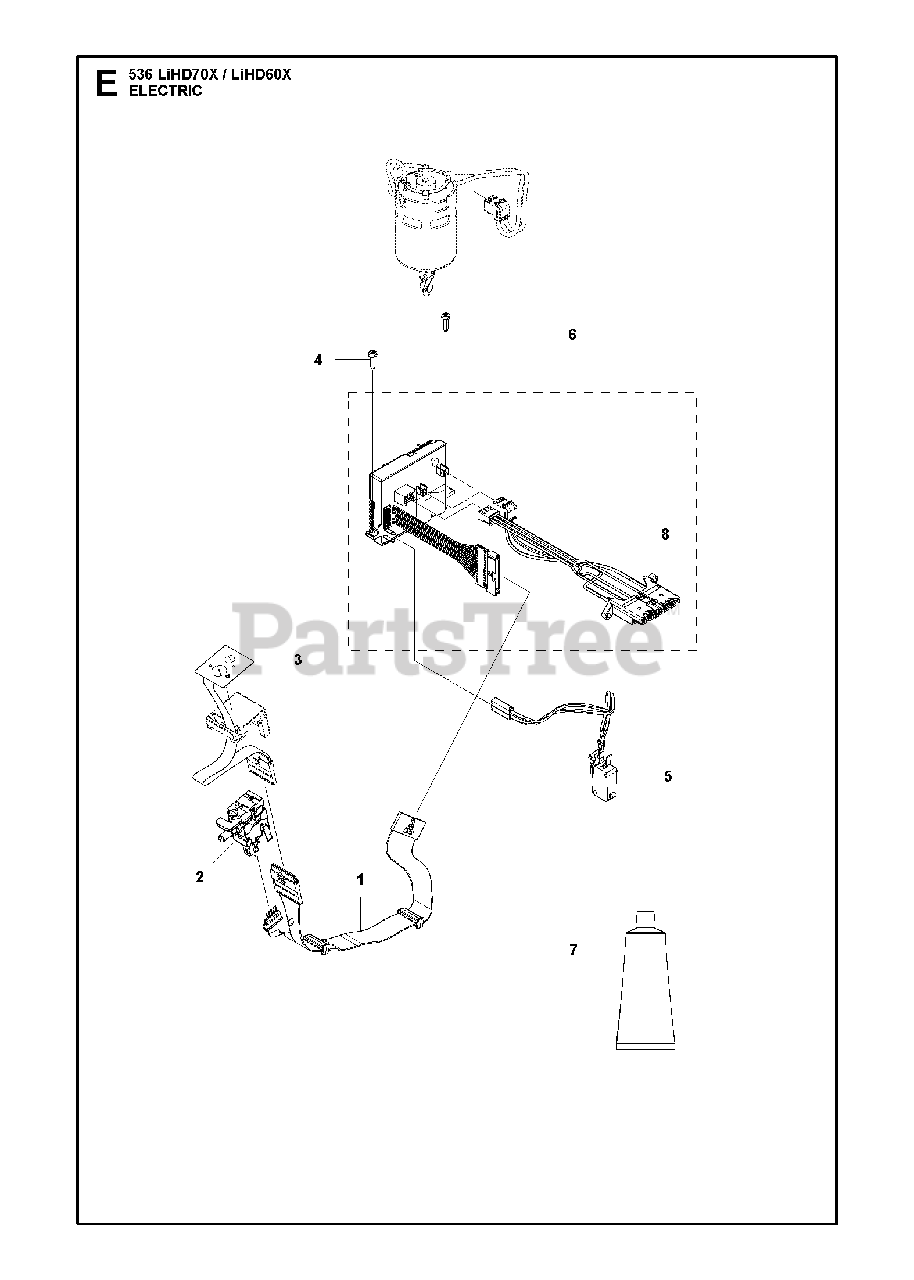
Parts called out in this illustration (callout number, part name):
1	WIRING ASSY TRIGGER HANDLE FOR
2	TRIGGER SWITCH
3	KEY PAD 2 BUTTON TRIMMER DC (T
5	WIRING ASSY FRONT GUARD
6	CONTROL UNIT PMDC SAFE HEDGE T
7	GREASE TUBE Q8 RUYSDAEL WR2
8	WIRING ASSY
